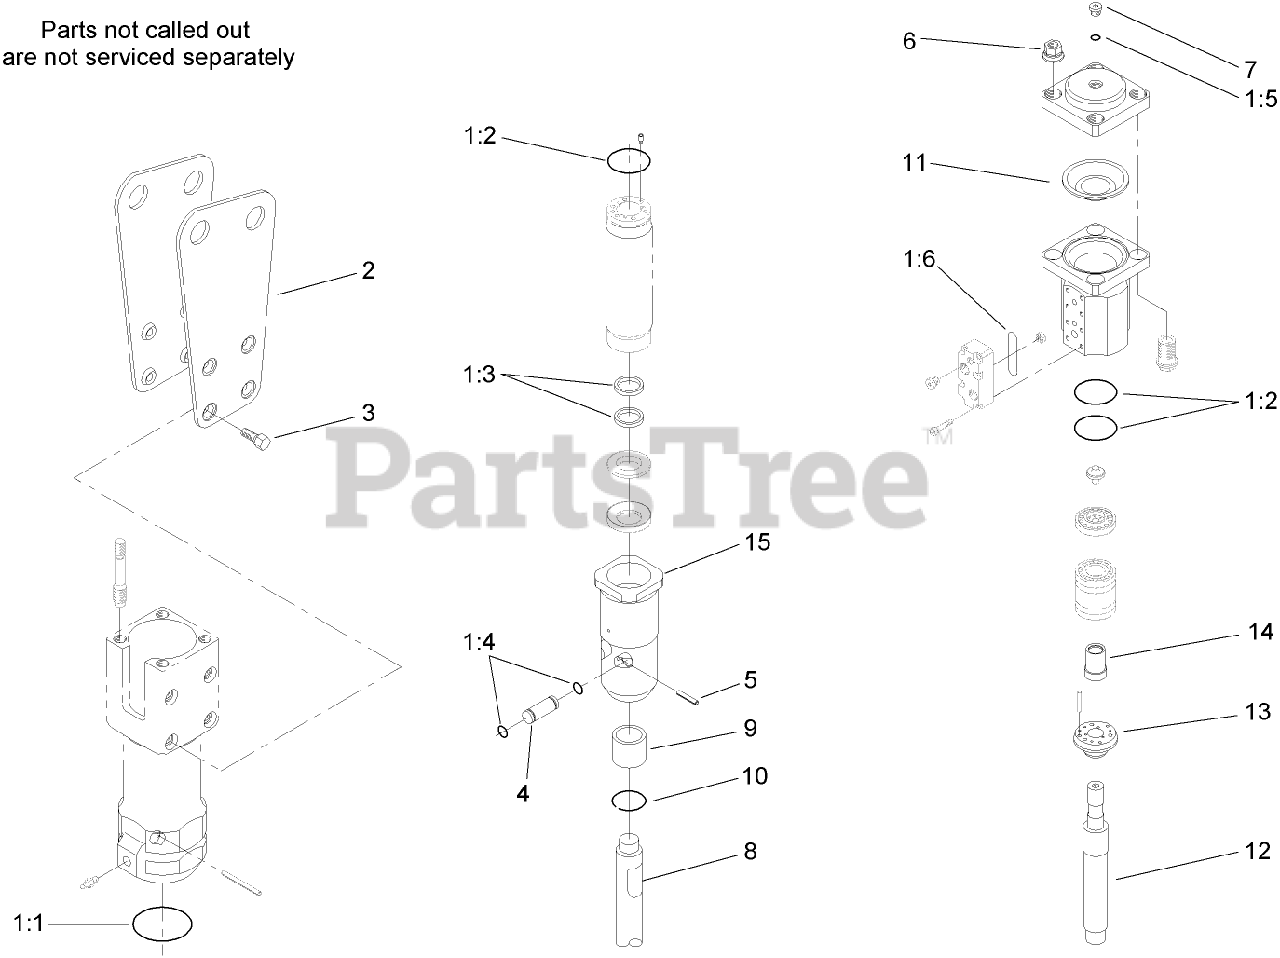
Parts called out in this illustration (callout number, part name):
1	KIT-SEAL
1:1	Seal-Dust
1:2	Seal-Dust
1:3	U-Joint
1:4	Seal-Dust
1:5	ORING-PLUG, ACCUMULATOR
1:6	Seal-Dust
2	PLATE-SIDE
3	SCREW-BREAKER
4	AXLE-RETAINING
5	PIN-ELASTIC
6	NUT-LOCKING
7	PLUG-INFLATING
8	TOOL-MOIL
9	Insert-Breaker
10	INSERT-RING, BREAKER
11	Diaphragm-Breaker
12	Piston-Breaker
13	Adapter-Guide
14	Distributor-Breaker
15	HOUSING-CHUCK
